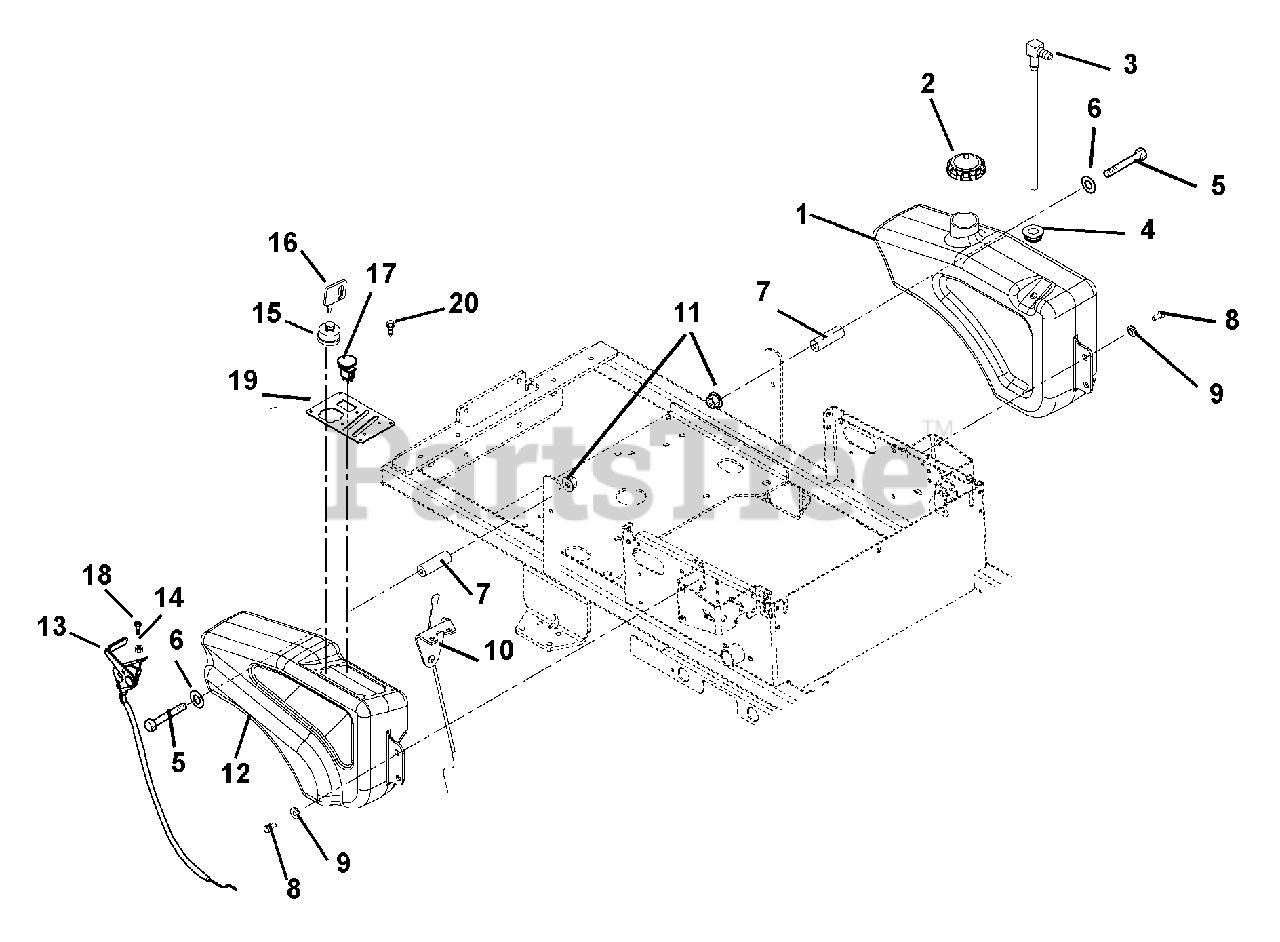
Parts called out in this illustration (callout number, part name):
1	Gas Tank HVZ
2	Fuel Cap
3	Fitting, Tank
4	Bushing, Flange .375 x 1.062 x .625
5	Bolt, Hex .31-18 x 3.50 Grade 5
6	Washer, Flat-Steel .38 x .875 x .083
7	Spacer, HVZ Tank Mount
8	Bolt, Hex .31-18 x .75 Grade 5
9	Shoulder Spacer
10	Cable, Choke Cable
10	Throttle/Choke Cable, HVZ 40"
11	Nut, .31-18 Nyloc Flange
12	Fender HVZ
13	Cable, Throttle
14	Nut-Locking-Nylon 10-24 with Insert
15	Key Switch
16	Key, w/cap
17	Switch, Clutch
18	Screw-Machine 10-24 x .75 Hex Washer Head
18	Screw, Tapping 10-24 x .50 Hex Washer Head Thread Rolling
19	Control Panel
20	Rivet, Plastic .195 Diameter
